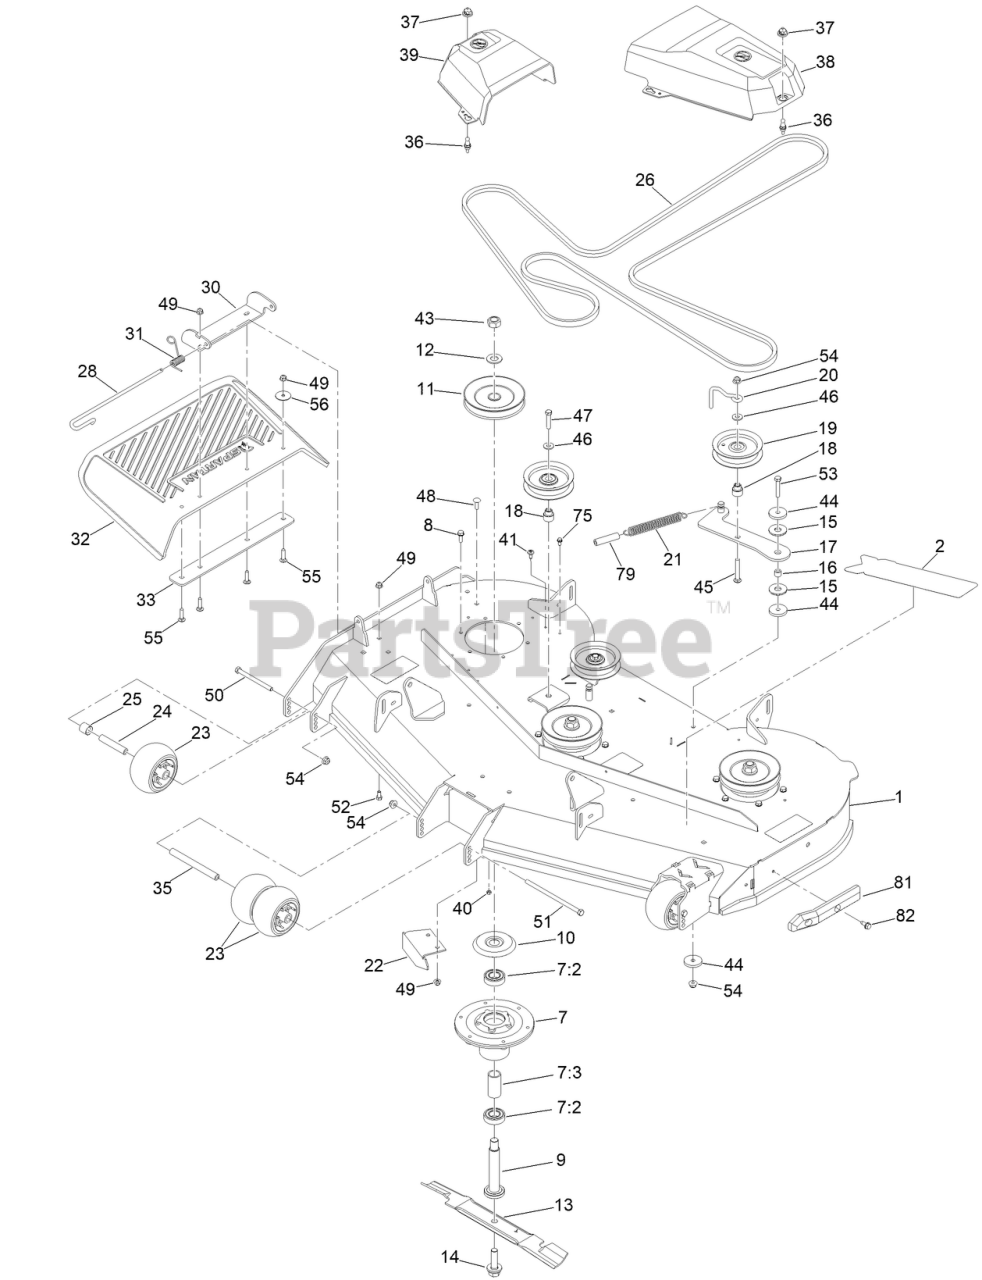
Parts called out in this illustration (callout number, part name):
1	54 IN DECK DECAL ASM
2	DECAL-XTF
7	SPINDLE ASM
7:2	BEARING-BALL
7:3	SPACER-BEARING
8	SCREW-TAPTITE
9	SHAFT-SPINDLE
10	SHIELD-BEARING
11	PULLEY
12	WASHER
13	BLADE-HI FLO
14	SCREW-BLADE
15	WASHER-FRICTION, COMPOSITE
16	SPACER
17	IDLER ARM ASM
18	BUSHING-IDLER
19	PULLEY-IDLER, FLAT
20	GUIDE-BELT, IDLER
21	SPRING-EXTENSION
22	BAFFLE-CUTOFF
23	ROLLER-SCALP, ANTI
24	TUBE-SPANNER
25	SPACER-AXLE, REAR
26	V-BELT (B SEC 174.25 EL)
28	PIN-CHUTE
30	BRACKET-DEFLECTOR, UPPER
31	SPRING-TORSION
32	DEFLECTOR-DISCHARGE
33	PLATE-DEFLECTOR
35	SPACER-WHEEL
36	STUD-BALL
37	GROMMET-BALL
38	COVER-BELT, LH
39	COVER-BELT, RH
41	SCREW-SHOULDER
43	NUT-HEX
44	WASHER-PLAIN
45	SCREW-CARR
46	WASHER-HARDENED
47	SCREW-HH
48	SCREW-CARR
49	NUT-HF, NI
50	SCREW-HH
51	SCREW-HH
52	SCREW-HH
53	SCREW-HH
54	NUT-HF, NI
55	SCREW-CARR
56	WASHER-FLAT
75	SCREW-HWH
79	HOSE-BREATHER
81	BUMPER-DECK
82	SCREW-HWHTF
